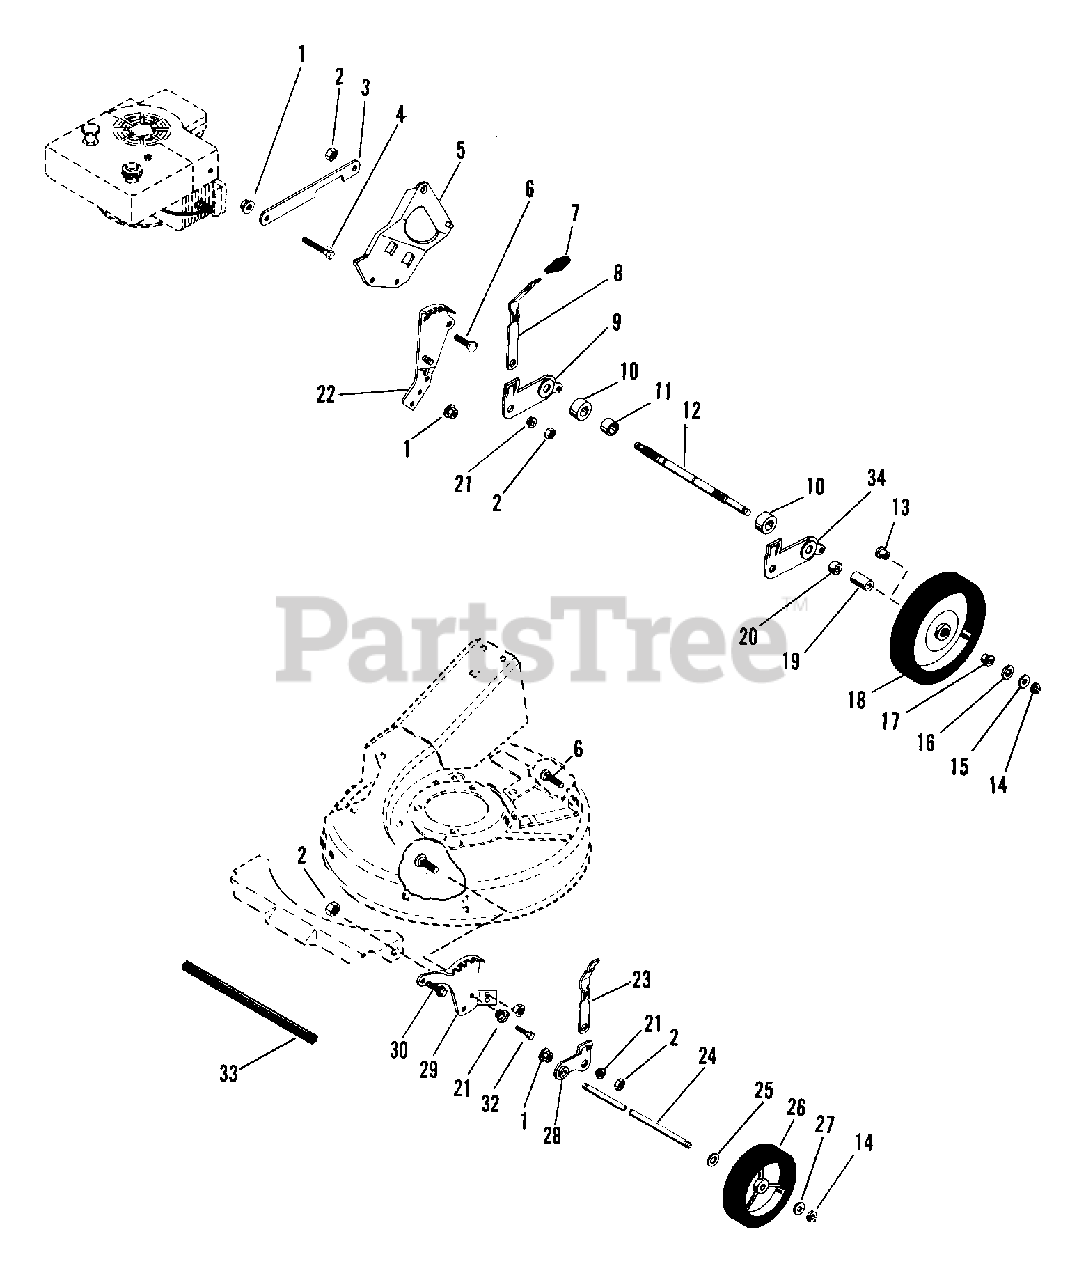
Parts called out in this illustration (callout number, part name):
1	NUT-FLG. .312-18 PL
2	NUT-LK .312-18 GR A PL
3	ANTIVIBRATION STRAP
3	ENGINE BRACE
4	BLT-RDHDSQNK .31-18X.75 GR5 PL
5	RH HANDLEBAR MTG. BRKT.
5	LH HANDLEBAR MTG. BRKT.
6	BLT-RDHDSQNK .312-18X.62SHTPL
8	HEIGHT ADJUSTMENT LEVER
9	REAR BRACKET & BEARING ASSEMBL
9	REAR BRACKET & BEARING ASSY RH
9	REAR ADJUSTMENT BRACKET R.H.
10	BRG-BALL .752X1.50X.45
10	BRG-BALL .625X1.383X.50
11	SPACER .78 X .74 X .39
12	REAR AXLE
12	REAR AXLE,5/8 DIA
12	REAR AXLE - PUSH MOWER
13	BSHG-FLG .625X.750X.750X1.125
14	RG-RTNG-EXT .438X.035
14	RG-RTNG-EXT .500X.042
14	RG-RTNG-EXT .500X.042 (E)
15	WSHR-FL-STL .630X1.005X.062 PL
15	WSHR-FL-STL .520X.827X.062 YZ
16	SEAL .625X.875X.125
17	BSHG-SLV .625X.750X.500
18	WHL COMP
18	WHL L.H.
18	WHL
18	REAR TIRE SERVICE ASSEMBLY
18	WHEEL
18	LH WHEEL
18	RH WHEEL
18	10 1/2 TIRE SKIN
19	TUBE
19	SPACER TUBE,PUSH LH
20	SPACER .75 X .25 X .88
20	SPACER
20	SPACER TUBE PUSH RH
20	SPACER TUBE, SELF PROPEL
21	BSHG-FLG .32X.500X.344X.880
22	REAR QUADRANT WELDMENT L.H.
22	REAR QUADRANT WELDMENT R.H.
22	QUADRANT, REAR - L.H.
22	REAR QUADRANT, R.H.
23	FRONT HEIGHT ADJUSTMENT LEVER
24	FRONT AXLE
25	WSHR-FL-STL .520X.827X.062 YZ
26	T/WHL ASSY 7X1.75 .5B
26	WHEEL
27	WSHR-FL-STL .505X.880X.072 PL
28	LEFT ADJUSTOR BRACKET ASSEMBLY
28	RIGHT ADJUSTOR BRACKET ASSEMBL
29	LEFT FRONT QUADRANT
29	RIGHT FRONT QUADRANT
29	FRONT QUADRANT, L.H.
29	FRONT QUADRANT, R.H.
30	SCR-TAP .375-16X.75 HWH PL TR
31	BLT-RDHDSQSHNK .31-18X.50 YZ
31	BLT-RDHDSQNK .31-18X1.25 SHTPL
32	BLT-HEX .31-18X.88 PL GR2
32	BLT-HEX .31-18X.75 PL GR2
33	BUMPER
34	REAR BRACKET & BEARING ASSEMBL
34	REAR ADJUSTMENT BRACKET L.H.
